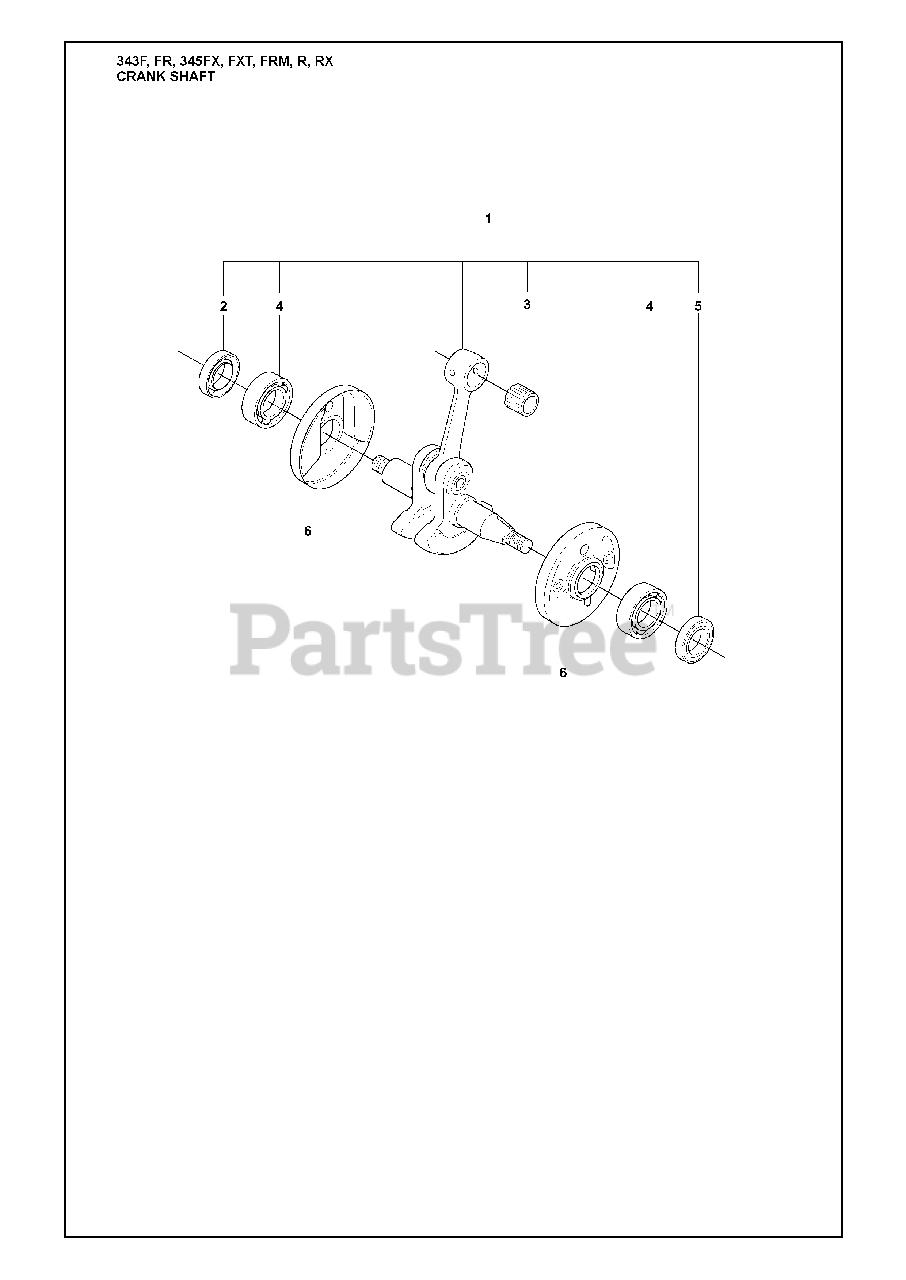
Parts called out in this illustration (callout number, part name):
1	CRANKSHAFT
2	SEALING RING
3	SUPPORT BUSHING
4	BALL BEARING-6202-C3 SKF
6	COLLAR
